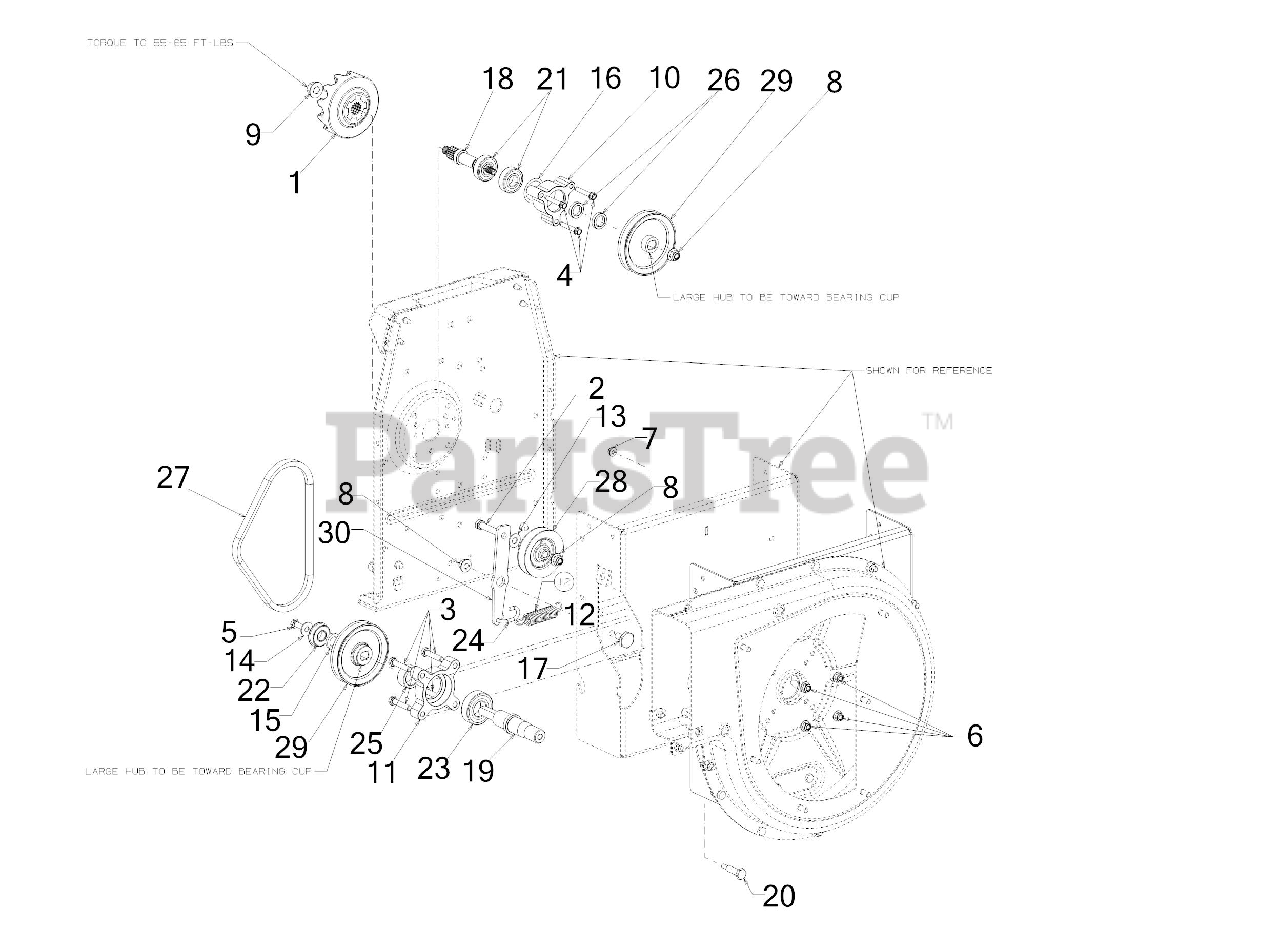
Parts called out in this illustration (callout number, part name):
1	DOG CLUTCH ASSEMBLY
2	HEX SCREW 3/8-16 x 1.75 GR5
3	SCREW 5/16-18 x 1.50 GR5
4	SCREW 1/4-20 X1.625
5	SCREW 5/16-18 x .750
6	FLANGE LOCK NUT 5/16-18
7	FLANGE LOCK NUT
10	BEARING CUP
11	BEARING HOUSING
12	EXTENSION SPRING
13	FLAT WASHER
14	FLAT WASHER
15	FLAT WASHER .632X1.00X.16
16	SHIM WASHER
17	SHIELD SCREW
18	DRIVE SPINDLE SHAFT
19	IMPELLER SPINDLE
20	SHOULDER SCREW
21	BALL BEARING
22	GROOVE BALL BEARING
23	BALL BEARING
24	EXTENSION SPRING HOOK
25	SLEEVE SPACER 25MM x 1.375 x 44
27	V-BELT 1/2 X 25.5
28	V-IDLER PULLEY A x 3.06 OD
29	DRIVE PULLEY
30	ILDER BRACKET
